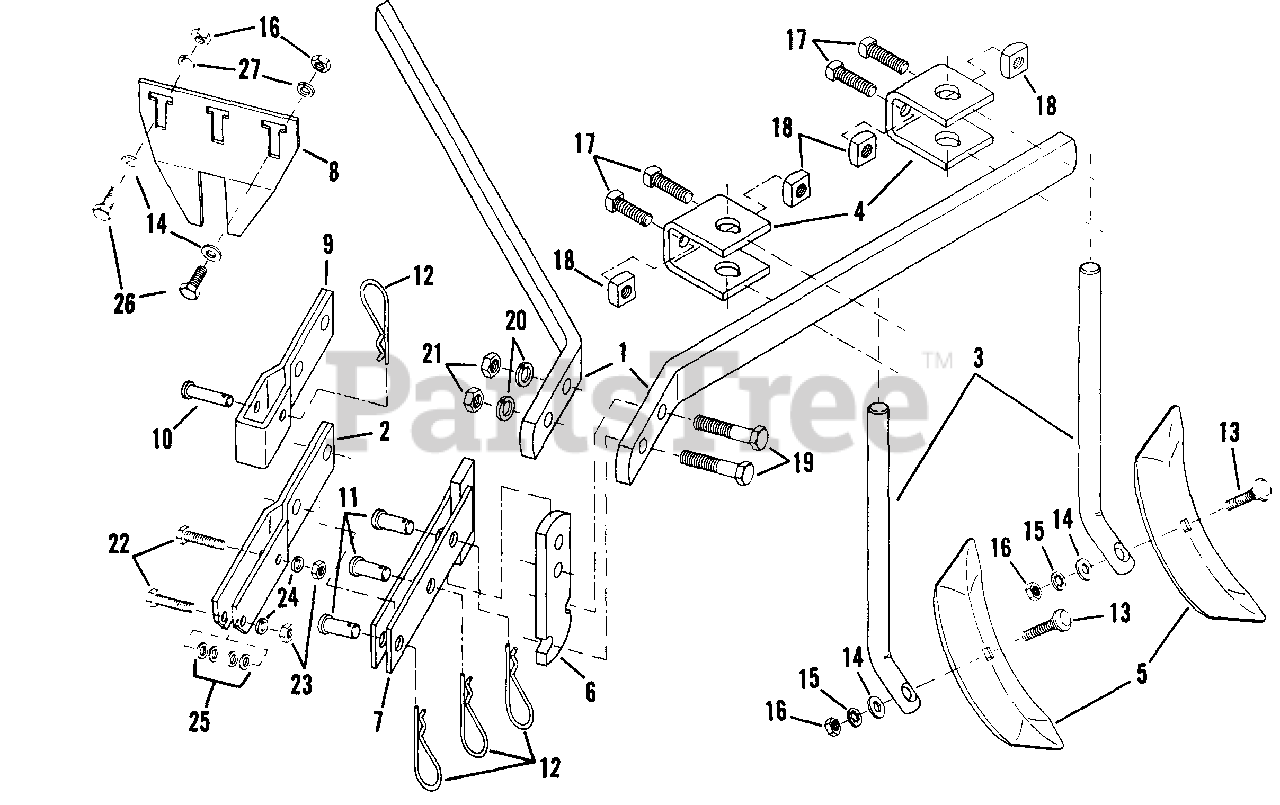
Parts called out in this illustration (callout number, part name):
1	(NLA) TOOL BAR
2	CLEVIS, Bracket
3	SHANK, Cultivator
4	CLAMP
5	SHOVEL, Double Point
6	(NLA) ADAPTER, Harrow
7	DRAW-BAR
8	CLEVIS, Support
9	BRACKET, Mounting
10	PIN, Clevis, 3/8 x 1 1/2"
11	PIN, Clevis, 1/2 x 1"
12	PIN, Hair 2.62"
13	BOLT, 3/8-16 x 1 1/2" Carriage
14	WASHER, 3/8" Flat
15	WASHER, 3/8 Internal Tooth Lock
16	NUT, 3/8-16 Hex
17	SETSCREW, 1/2-13 x 1 1/4" Square Head
18	NUT, 1/2-13 Square
19	SCREW, 1/2-13 x 2" Hex Head Cap
20	WASHER, 1/2 Split Lock
21	NUT, 1/2-13 Hex
22	SCREW, 5/16-18 x 1 1/2" Hex Head Cap
23	NUT, 5/16-18 Hex
24	WASHER, 5/16 Split Lock
25	WASHER, 5/16 Flat
26	SCREW, 3/8-16 x 3/4" Hex Head Cap
27	WASHER, 3/8 Split Lock
